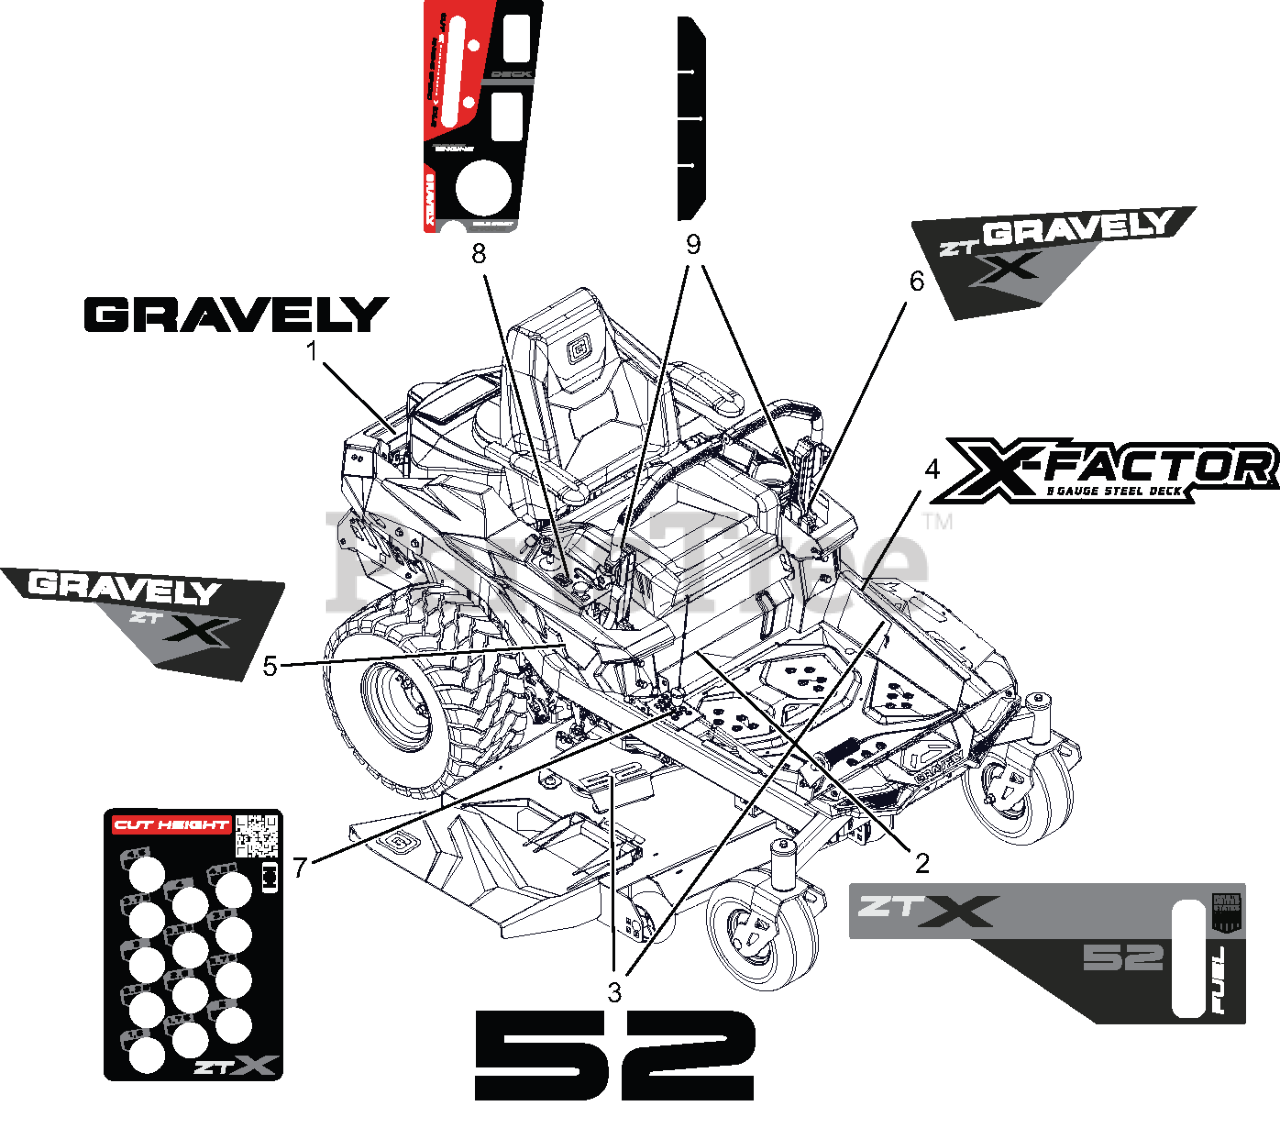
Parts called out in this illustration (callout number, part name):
1	DECAL- GRAVELY
2	DECAL- ZTX 52-KICK PLATE
3	DECAL- DECK 52"
4	DECAL- DECK X-FACTOR
5	DECAL- ZT X FENDER RH
6	DECAL- ZT X FENDER LH
7	DECAL- HEIGHT OF CUT-X
8	DECAL- CONTROL PANEL-GRAVELY
9	DECAL- HIRTH INDICATOR
